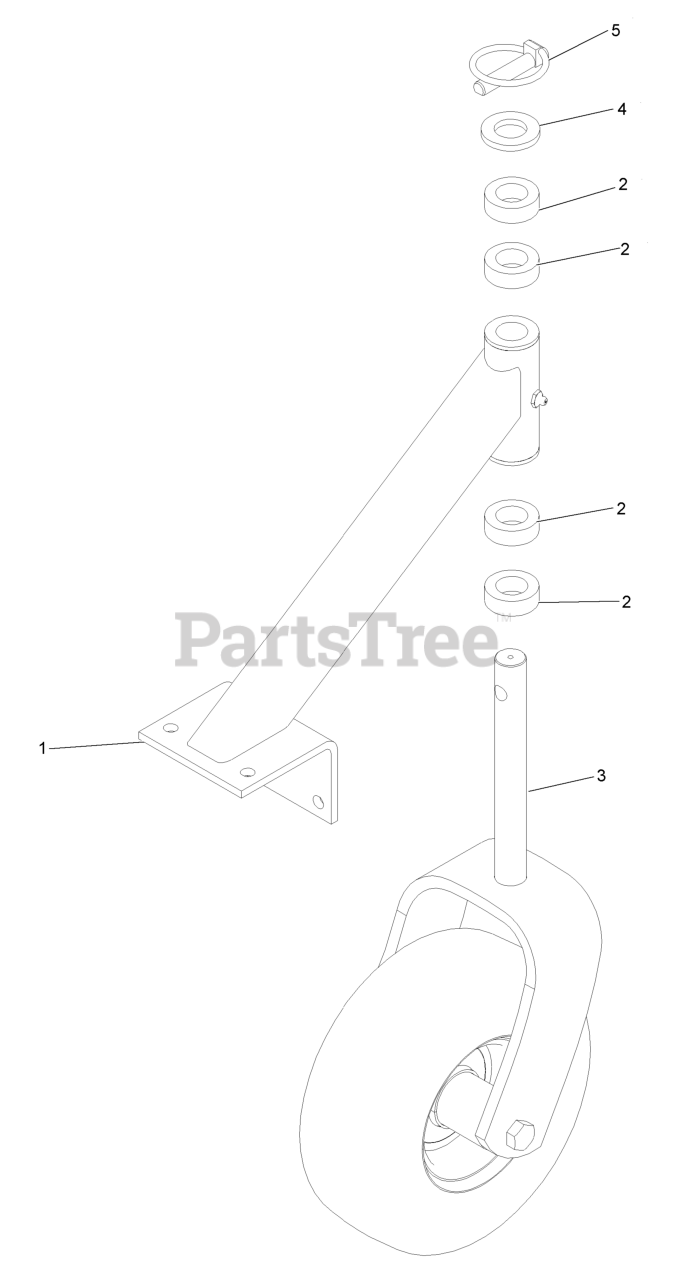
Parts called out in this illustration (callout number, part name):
1	ASM,CSTR SUPPORT W/WEIGHT
2	SPACER-CASTER
3	ASM,CASTER/WHEEL
4	WASHER-FLAT
